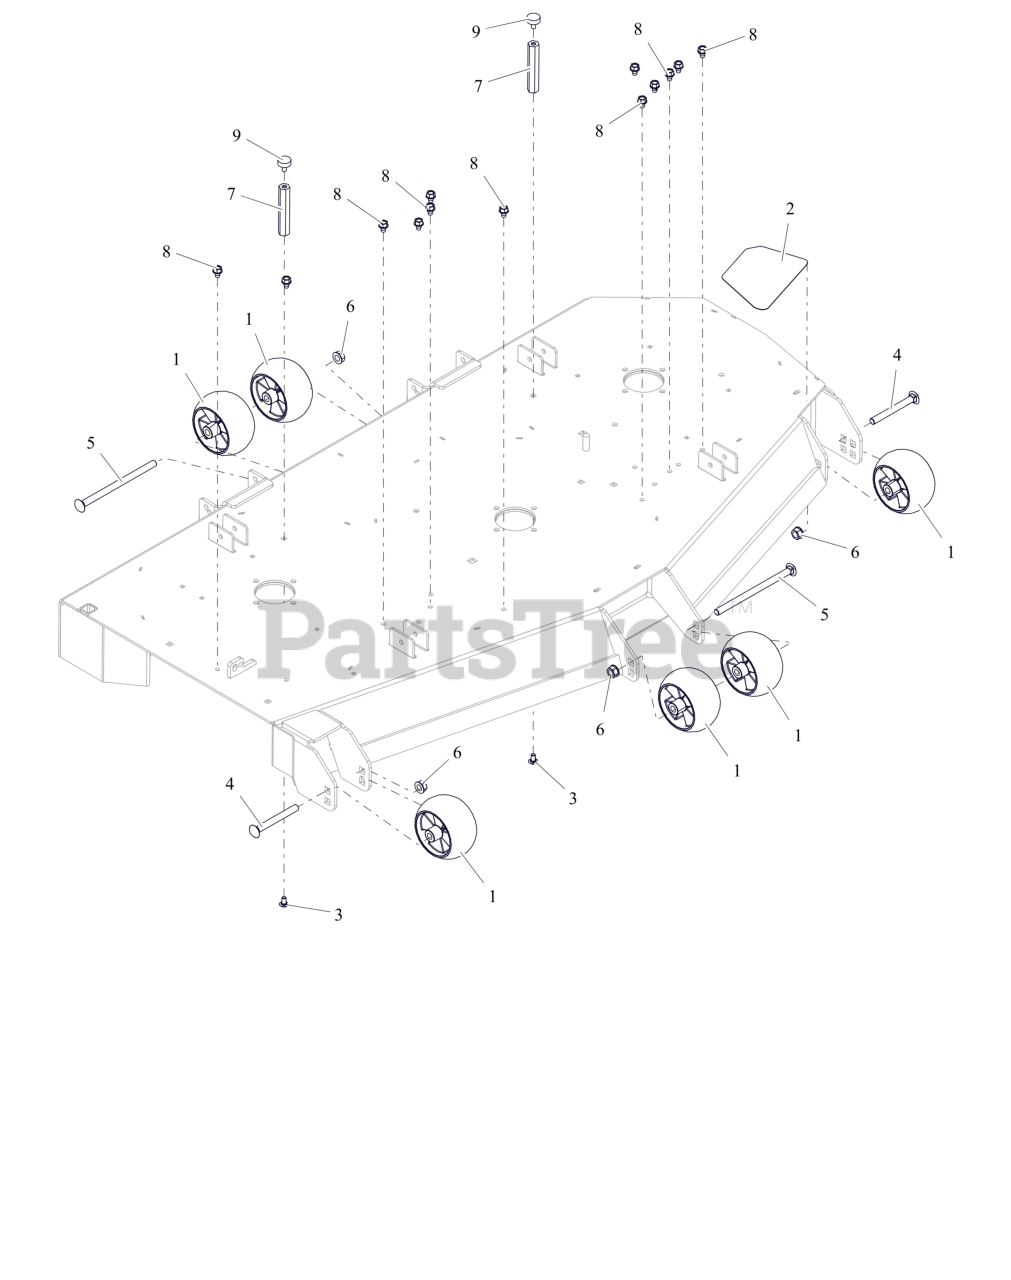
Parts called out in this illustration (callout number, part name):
1	WHEEL, ANTI SCALP - 5X3 CTR W/RIBS
2	GRIP, STEP ANTI SKID
3	BTL,RHSSN .313-18 X 0.625 G5 ZCC
4	BLT,RHNS .50-13X4.50 G5 ZCC NS
5	BLT,RHSN .50-13X8.00 G5 ZCC NS
6	NUT-LK-CTR-FLG .500-13 GG ZCC
7	NUT, COUPLING .312-18 X 4.295
8	SCR,TAP .375-16X.50 HWH TR ZCC
9	BUMPER, RUBBER
